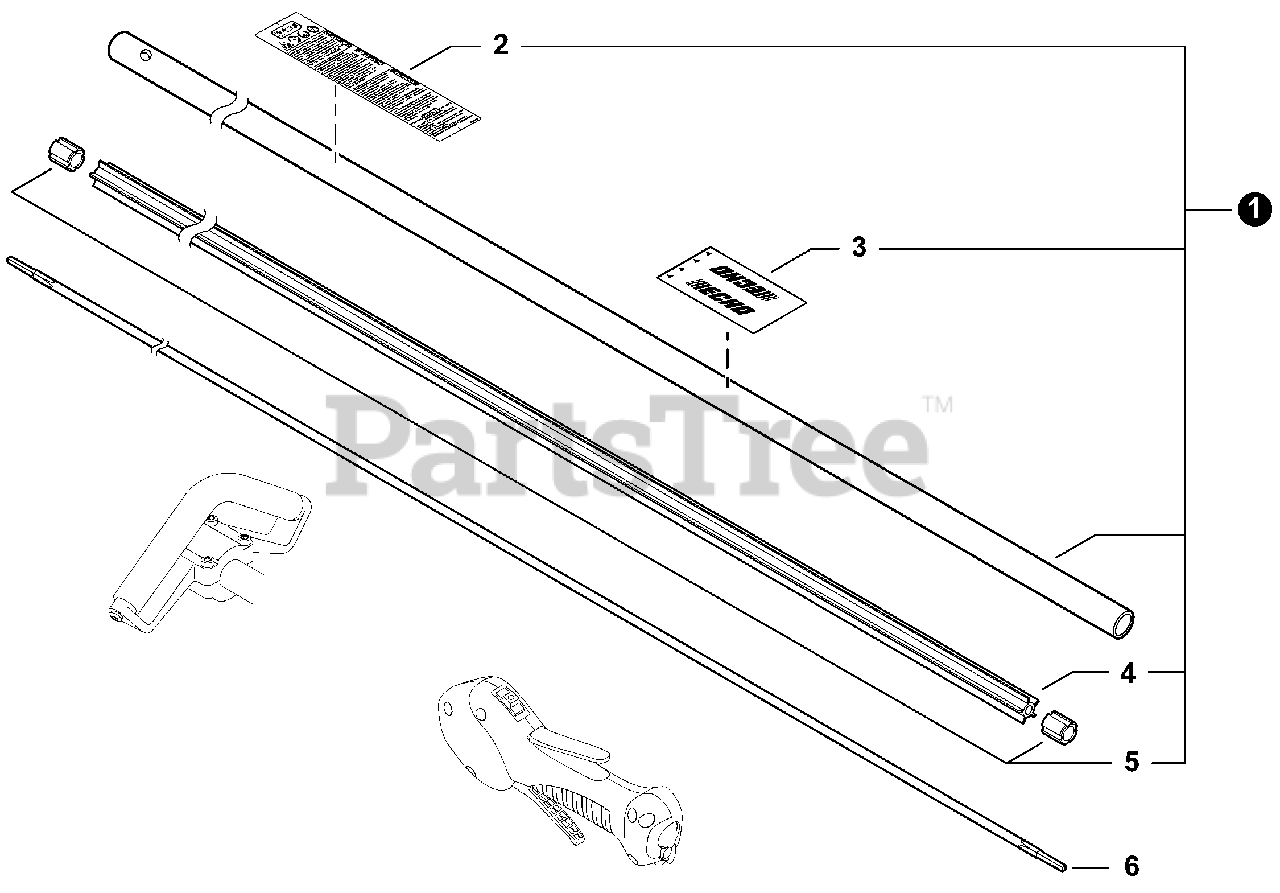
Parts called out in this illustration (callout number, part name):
1	MAIN PIPE ASSY
2	LABEL, CAUTION
3	LABEL, HANDLE LOCATION
4	LINER, FLEXIBLE 21.6×1420
6	DRIVESHAFT - FLEXIBLE
